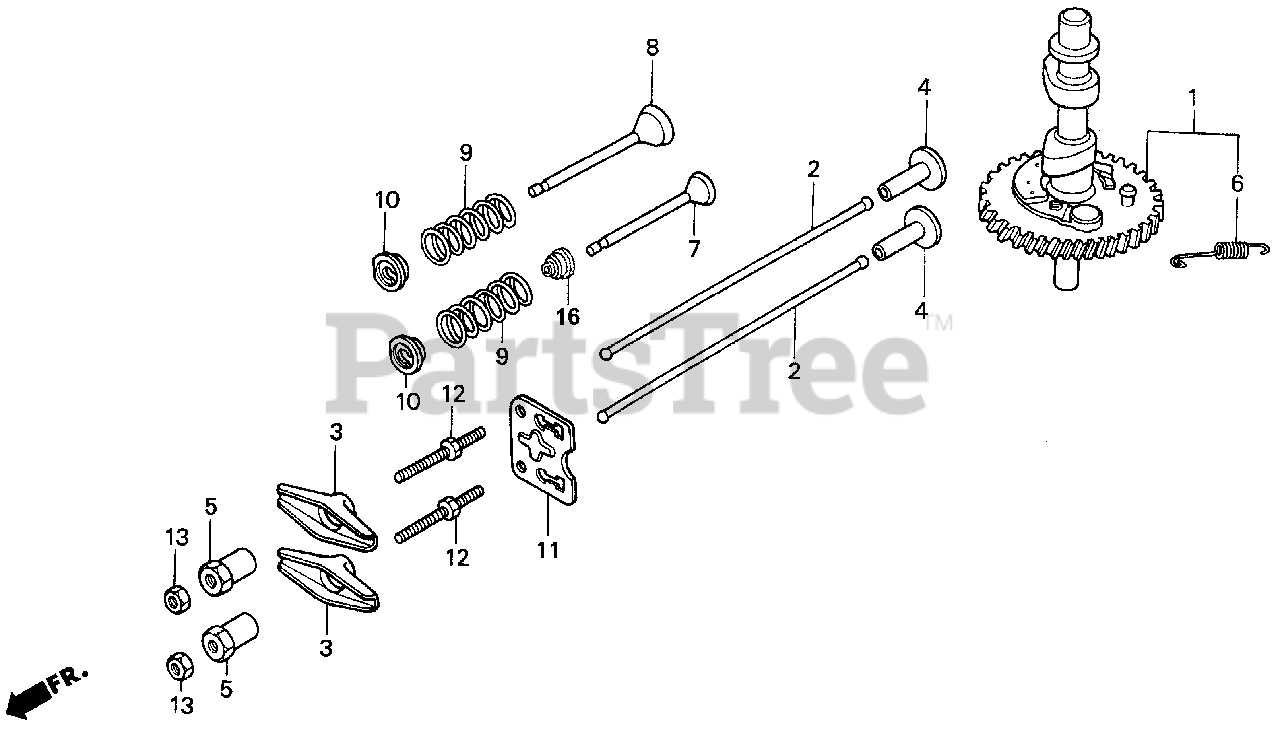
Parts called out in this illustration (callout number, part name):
1	CAMSHAFT ASSY.
2	ROD, PUSH
3	ARM, VALVE ROCKER
4	LIFTER, VALVE
5	PIVOT, ROCKER ARM
6	SPRING, WEIGHT RETURN
7	VALVE, IN.
8	VALVE, EX.
9	SPRING, VALVE
10	RETAINER, IN. VALVE SPRING
11	PLATE, PUSH ROD GUIDE
12	BOLT, PIVOT (8MM)
13	NUT, PIVOT ADJ.
16	SEAL, VALVE STEM
